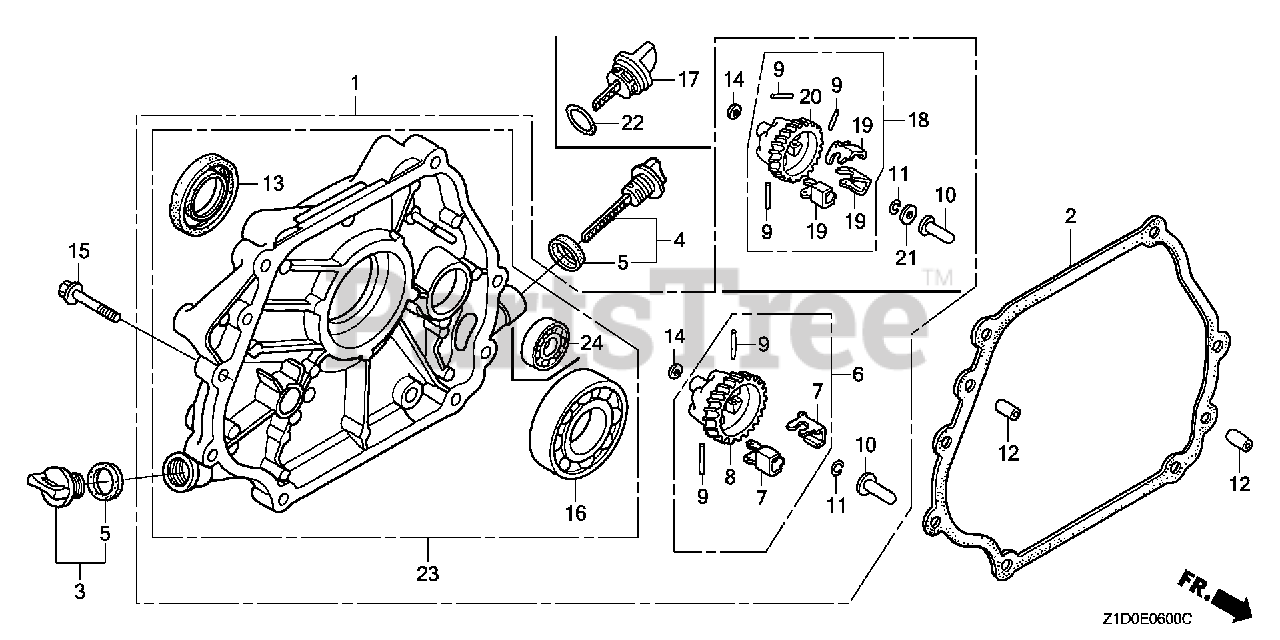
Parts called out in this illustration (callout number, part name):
1	COVER ASSY., CRANKCASE
2	GASKET, CASE COVER
3	CAP ASSY., OIL FILLER (BLACK)
4	CAP ASSY., OIL FILLER
5	GASKET, OIL FILLER CAP
6	GOVERNOR ASSY.
7	WEIGHT, GOVERNOR
8	HOLDER, GOVERNOR WEIGHT
9	PIN, GOVERNOR WEIGHT
10	SLIDER, GOVERNOR
11	CLIP, GOVERNOR HOLDER
12	PIN, DOWEL (8X12)
13	OIL SEAL (30X46X8) (NOK ASIA)
14	WASHER, PLAIN (6MM)
15	BOLT, FLANGE (8X35)
16	BEARING, RADIAL BALL (6206)
